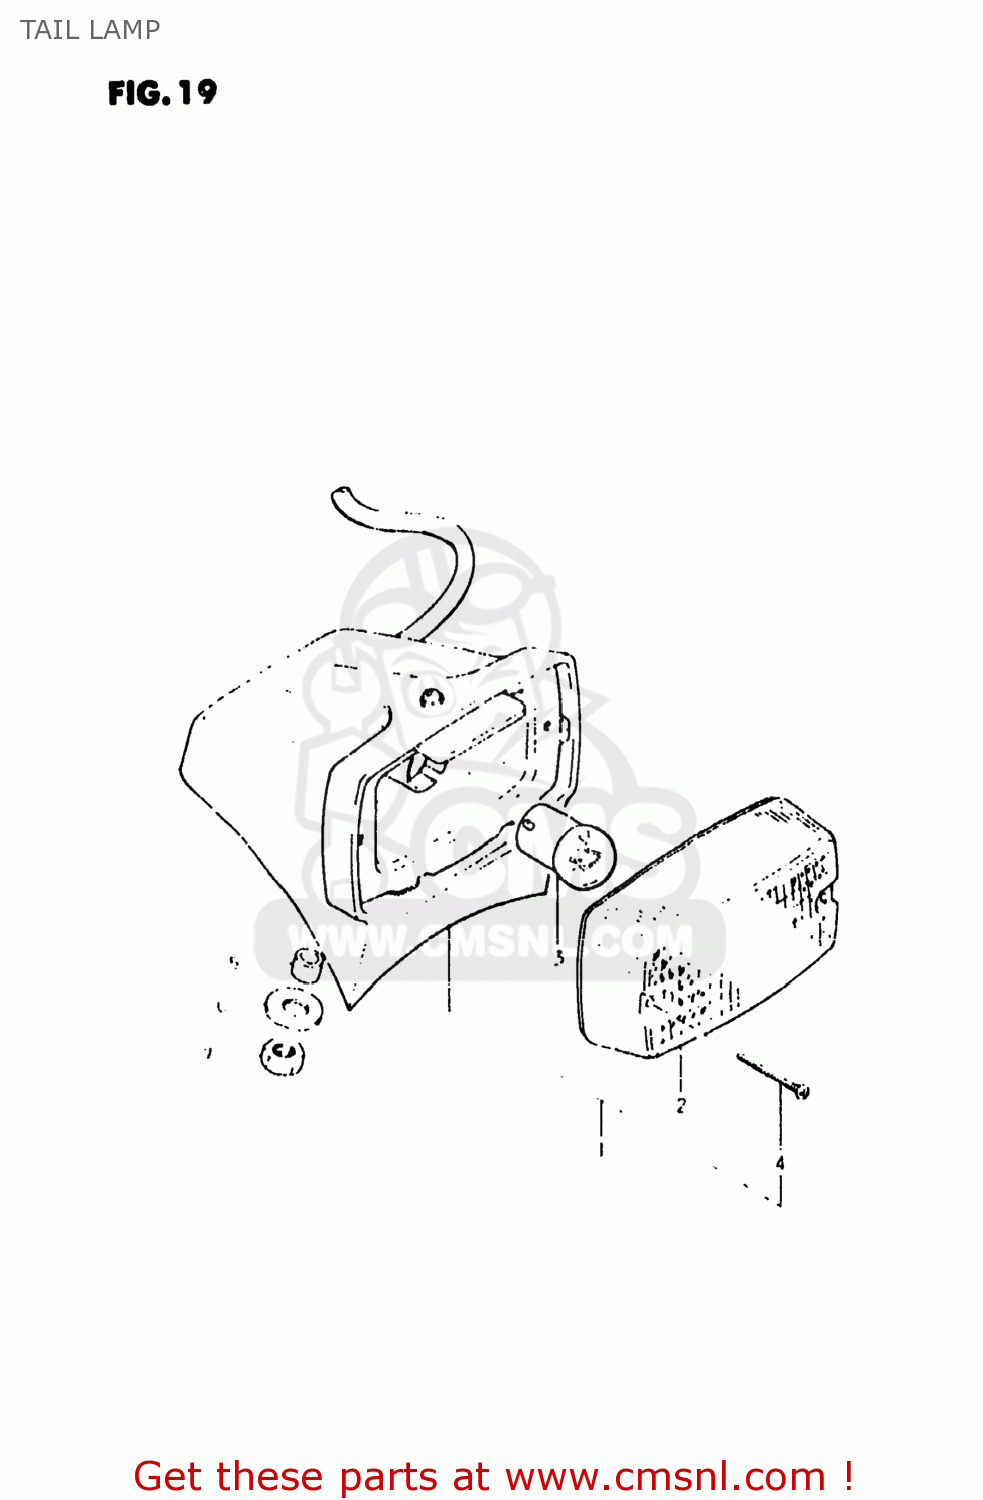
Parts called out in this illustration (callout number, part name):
1	LAMP ASSEMBLY,REAR COMBINATION
2	LENS
3	SCREW,REAR COMBINATION LAMP LENS
4	BULB(6V5W,TOKAI DENSO)
5	SPACER (6.1X9X9)
6	WASHER
7	NUT
